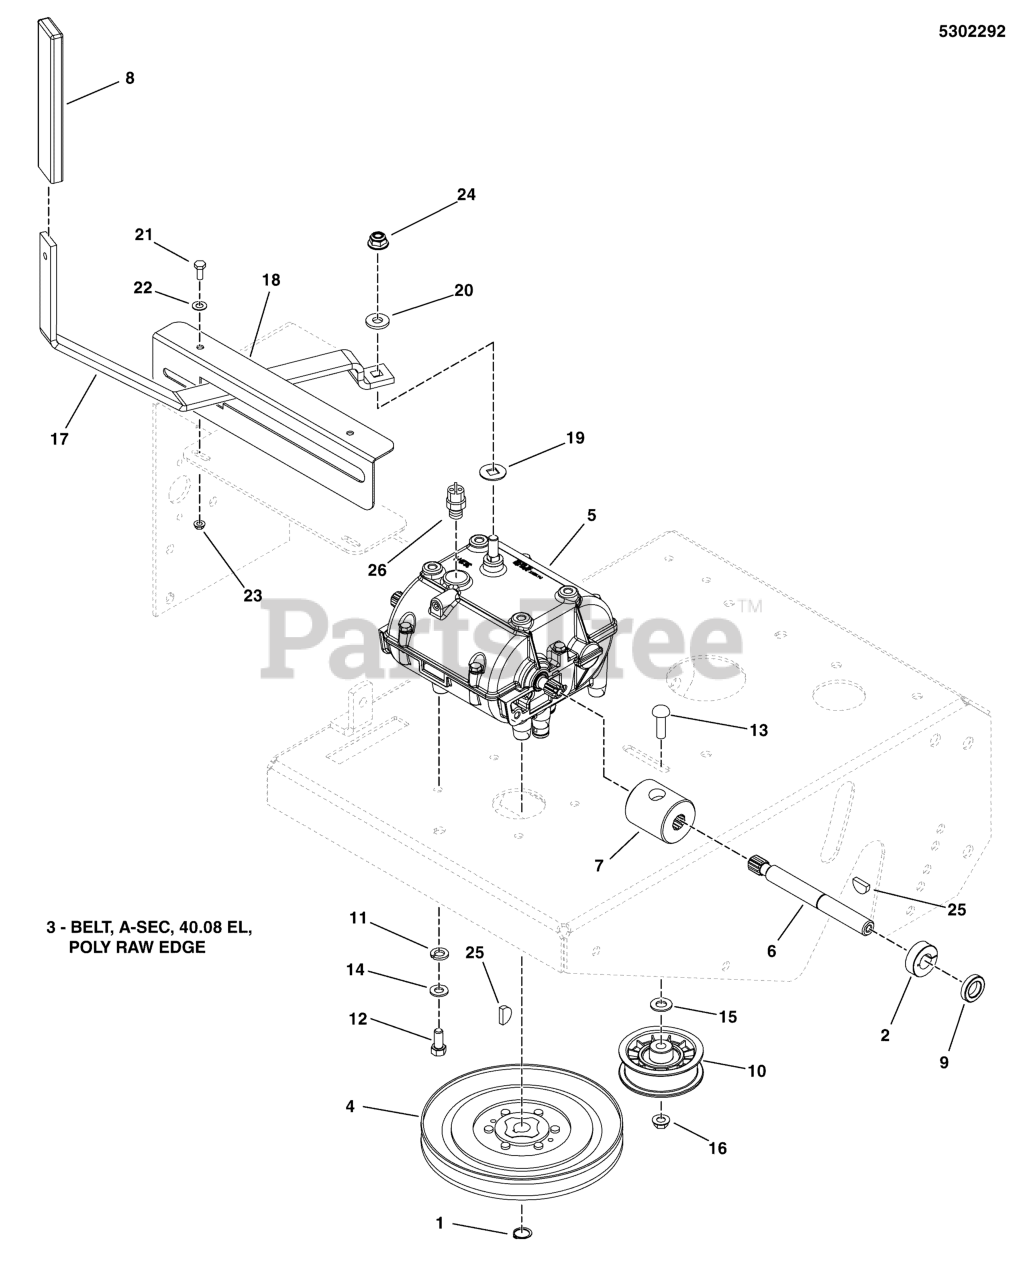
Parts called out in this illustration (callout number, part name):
1	RING, RETAINING
2	COLLAR, 5/8 SPLIT
4	PULLEY-DRIVE-V, 7.85OB, .625ID, .93W,STL
5	GEARBOX, MODEL 700-070A
6	SHAFT, GEARBOX OUTPUT
7	COUPLER, GEARBOX OUTPUT
8	GRIP, FOAM, 1/4 X 1 X 6-3/4"
9	SPACER, .63 X 1.06 X .23
10	IDLER PULLEY ASSEMBLY
11	WASHER, 5/16 LOCK CZ
12	BOLT, 5/16-18 X 3/4 GD5
13	RHSSNB, 3/8C X1-3/4 G5 ZP
14	WASHER, 5/16" SAE
15	WASHER, 3/8 SAE
16	NUT, 3/8-16 HEX NYLOCK FLANGE
17	BGF GEAR SELECTOR HANDLE - RED
18	GUIDE, GEAR SELECTOR - RED
19	WASHER, TRANSMISSION, SW5
20	BELLEVILLES WASHER, .38 X .875 X .109
21	BOLT, 1/4-20 X 3/4, GD5
22	WASHER, 1/4 SAE
23	NUT, 1/4-20 HEX SERR. FLANGE
24	NUT, 3/8-24 HEX NYLON LOCK
25	KEY, #9 HI-PRO WOODRUFF
26	SWITCH, GEARBOX NEUTRAL
